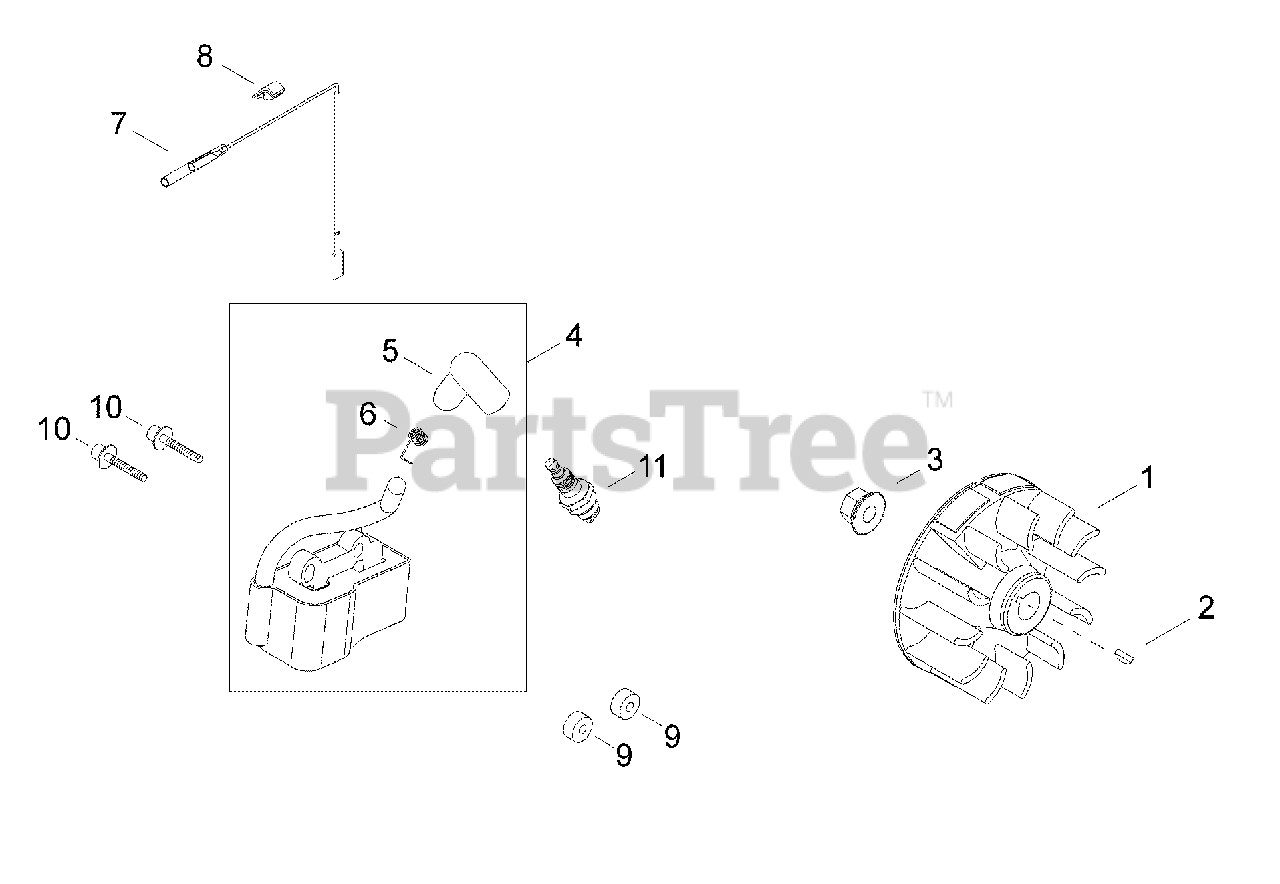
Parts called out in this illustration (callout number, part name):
1	FLYWHEEL
2	KEY - 3X10
3	NUT - 8
4	IGNITION COIL ASSY
5	CAP, SPARK PLUG
6	TERMINAL, SPARK PLUG CAP
7	LEAD - IGNITION
8	GROMMET
9	INSULATOR
10	SCREW - 4X26
11	SPARK PLUG -- CMR-5H
